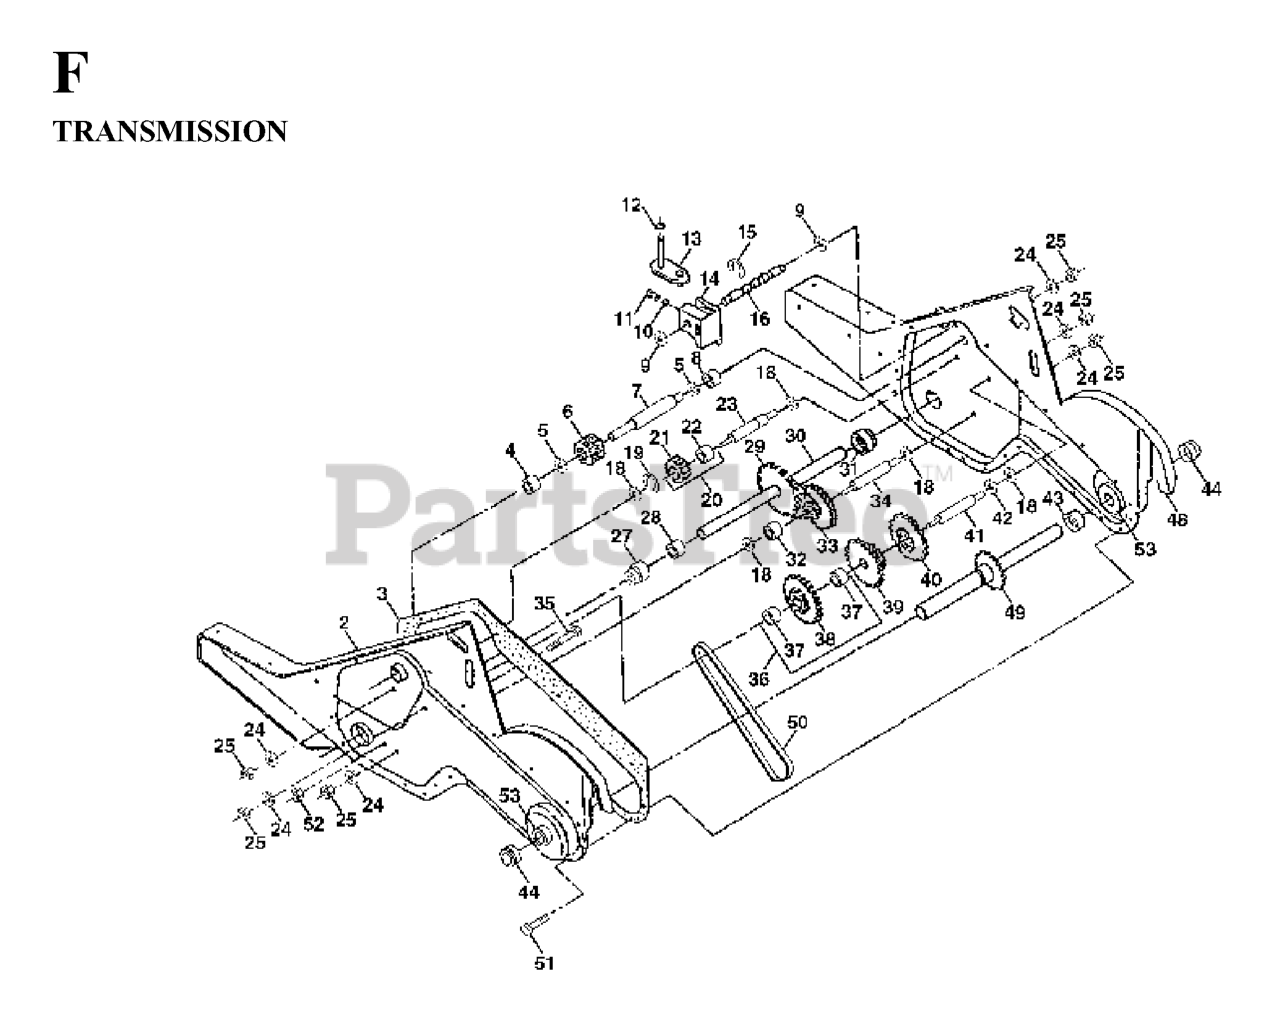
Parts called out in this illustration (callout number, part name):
1	TRANSMISSION ASSY
2	GEARCASE LH W/BRG
3	GASKET TI
4	NEEDLE BRNG LT
5	THRUST WASHER
6	GEAR.PINION.INPUT
7	SHAFT.INPUT."D".TILLER
8	BEARING TI
9	WASHER, SEAL (2 2)
10	STEEL BALL KIT
11	SPRING-SHIFT CRT
13	BRACKET ASM.SHIFT.CRT
14	SHIFT FORK TI
16	SHAFT.SHIFTER.TILLER
20	GEAR ASSY CRT
21	GEAR-REV IDLR CRT
22	NEEDLE BEARING TI
24	LOCKWASHER
25	NUT.ASF.HEX.7/16
27	BEARING, SHAFT LH CRT
30	GROUND SHAFT ASS'Y
31	BEARING, SHAFT RH CRT
33	SPRCKT 8 GEAR CRT
34	SHAFT.SECONDARY.REDUCTION.CRT
35	SCRW WHIZ LOK CRT
36	SPROCKET.ASM.W/BEARING.TILLER
37	BEARING
38	SPROCKET, TINE
41	SHAFT.REDUCTION.TILLER
42	BRNG RACE T
44	SEAL ASM, OIL
48	GEARCASE RH W/BRG
49	TINE SHAFT
50	CHAIN.TILLER
51	SCREW
53	BEARING KIT
